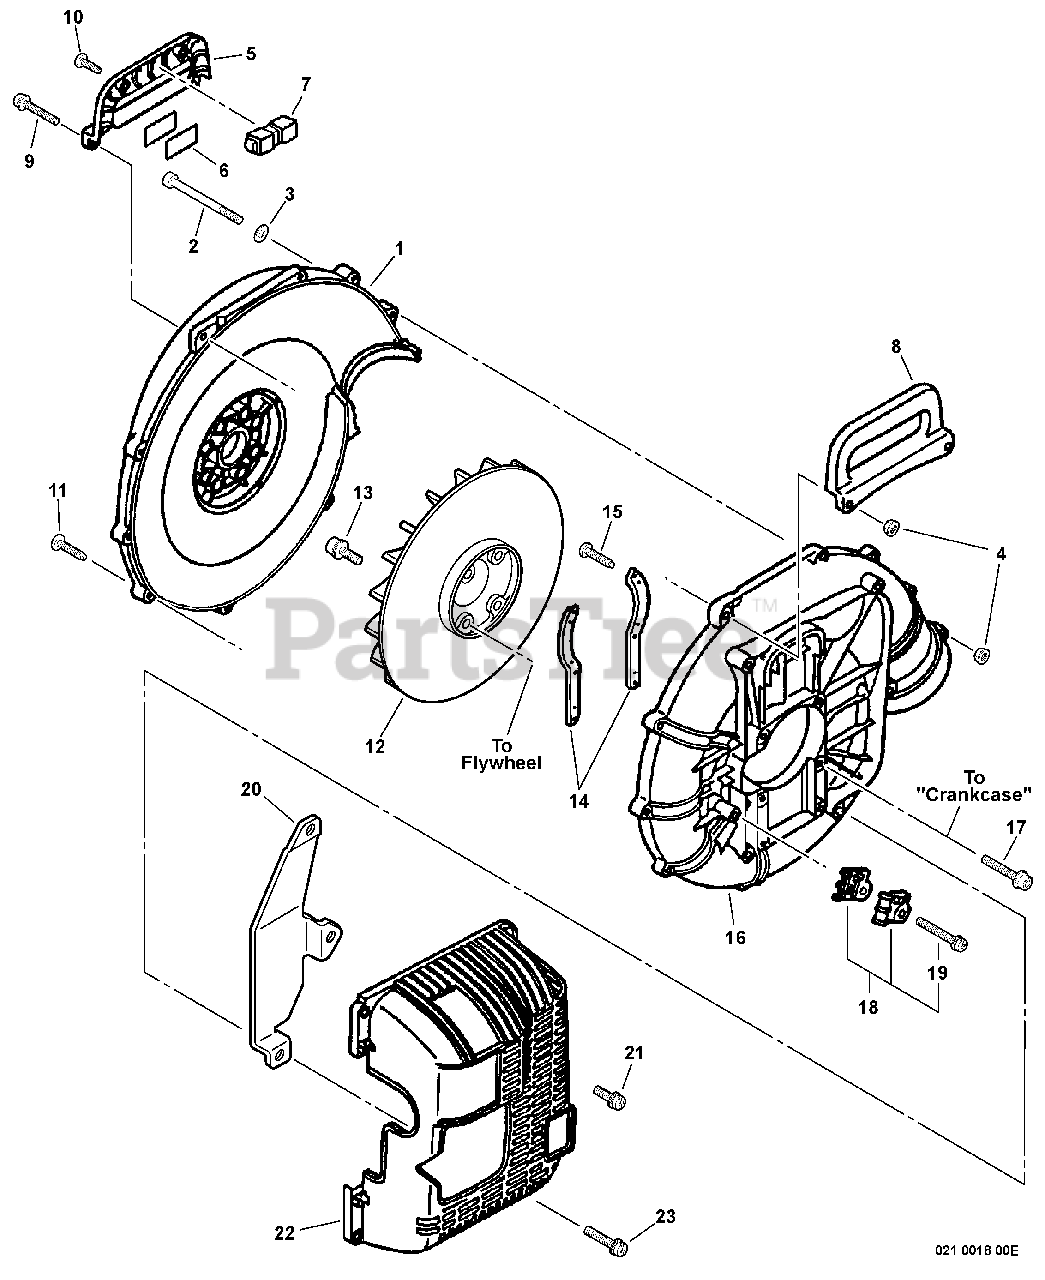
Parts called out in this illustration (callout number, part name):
1	COVER, FAN - INNER
2	SCREW - 5X60
3	WASHER - 5
4	NUT - 5 -- FLANGE
5	HANDLE - INNER -- GRAY
7	WEIGHT, HANDLE
8	HANDLE - OUTER -- GRAY
9	SCREW - 5X45
10	SCREW - 5X16 -- TAPPING
11	SCREW - 5X30
13	SCREW - 5X20
14	BRACKET, ENGINE
15	SCREW - 3X12 -- TAPPING
16	COVER, FAN - OUTER
17	SCREW - 5X32
18	CABLE HOLDER KIT
19	SCREW - 5X25
20	INSULATOR
21	SCREW - 5X10
22	COVER, ENGINE
23	SCREW - 5X18
